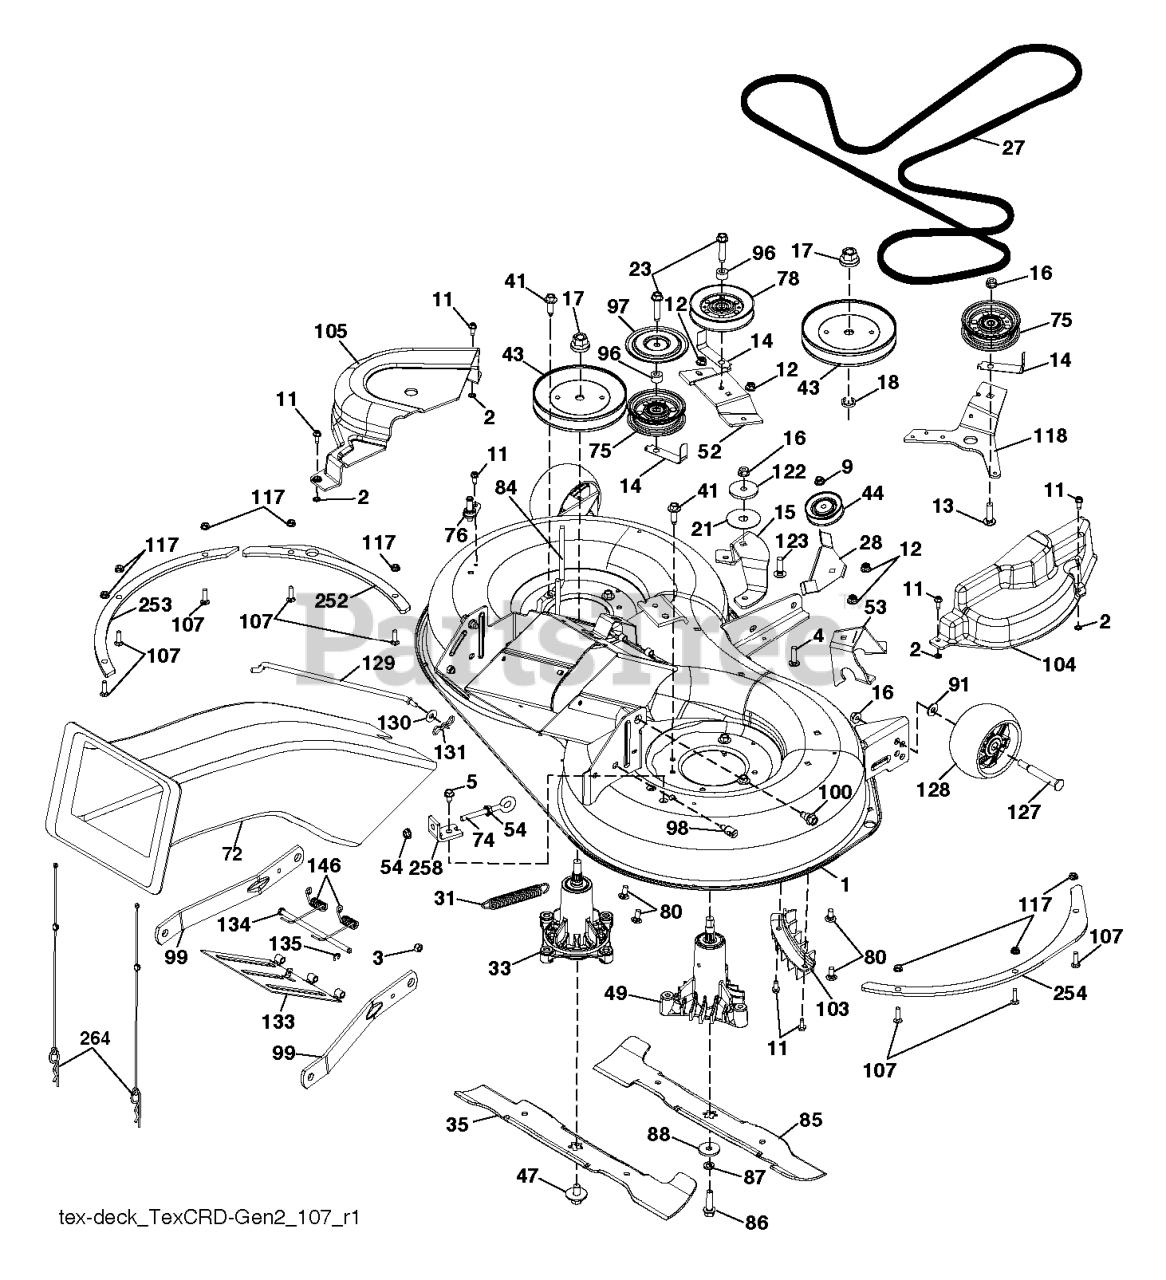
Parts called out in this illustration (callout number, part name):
1	Service Kit
2	PALNUT 1/4
3	GSPW Nuts
4	BOLT.CARRIAGE.5/16-18
5	BOLT.5/16HEX.WHS.HD
9	NUT HEX FLG NYLOCK BLK 5_16-1
11	SCREW.1/4-20X5/8
12	NUT HEXAGON FLANGE 5/16-18 ST
13	GSPW Bolts
14	KEEPER, BELT IDLER
15	BRACKET CRD IDLER ARM MOUNT BL
16	NUT LOCK FLG 3/8-16 UNC
18	WASHER.SPACER.MANDREL
23	BOLT;HEX_3/8-16 X 1.78.CLRZINC
27	BELT.97CRD.ELECTRIC.DECK.DRIVE
28	KEEPER 97 CRD ANGLED IDLER KEE
31	SPRING.EXTN.42.FCS.TR.DECK.DRV
33	KIT.MANDREL.NONGREASE.TALL
35	BLADE.3N1.LH.CRD.97
41	BOLT.HEX.WASHR.HED.313-18X1.19
43	PULLEY.MANDREL.5.0.PD.38"
44	PULLEY.V-IDLER.
47	SCREW.SEMS.7/16-20X1.HEX.HEAD
49	MANDREL ASM.CRD RH 6PT STAR
52	BRACKET 97 CRD CENTER V-IDLER
53	BRACKET 97 CRD ANGLED V-IDLER
54	GSPW Hardware
72	CHUTE.SLOTTED.HOLES.TEX.CRD.II
74	GSPW Bolts
76	PORT.WASHOUT
78	REPL BY 532 1467-63
80	GSPW Bolts
84	BELT KEEPER.MANDREL.38"COATED
85	BLADE.3N1.RH.CRD.97
86	BOLT.3/8-24X1.25GR8. LHTHRD
88	WASHER.BLADE
96	SPACER
97	PROTECTOR
98	STUD.FASTNER.W/ANTI-ROTATE
99	ARM.SUSPENSION.MOWER.R
100	BOLT.SHOULDER
103	GUARD GUARD FRONT VENT
104	GUARD 97CRD RH MANDREL COVER;
105	MANDREL MANDREL COVER LH
107	BOLT CUP HEAD SQUARE NECK 1/4-
117	NUT T
118	ARM 97 CRD IDLER ARM BLACK E-C
122	SPACER.RETAINER.MOWER
128	WHEEL.GAUGE.RALLY
129	ROD ROD. SWAY CRD GEN II
130	WASHER
131	PIN.COTTER.5/16.BOW TI
133	DOOR
135	E-RING.5/16"
146	SPRING SPRING: EZ MULCH DOOR
252	PLATE.REINFORCEMENT.X431
253	PLATE.REINFORCEMENT.LHS.X431
254	PLATE.REINFORCEMENT.LHS.X431
258	BRACKET CRD ELEC DECK DRIVE TE
